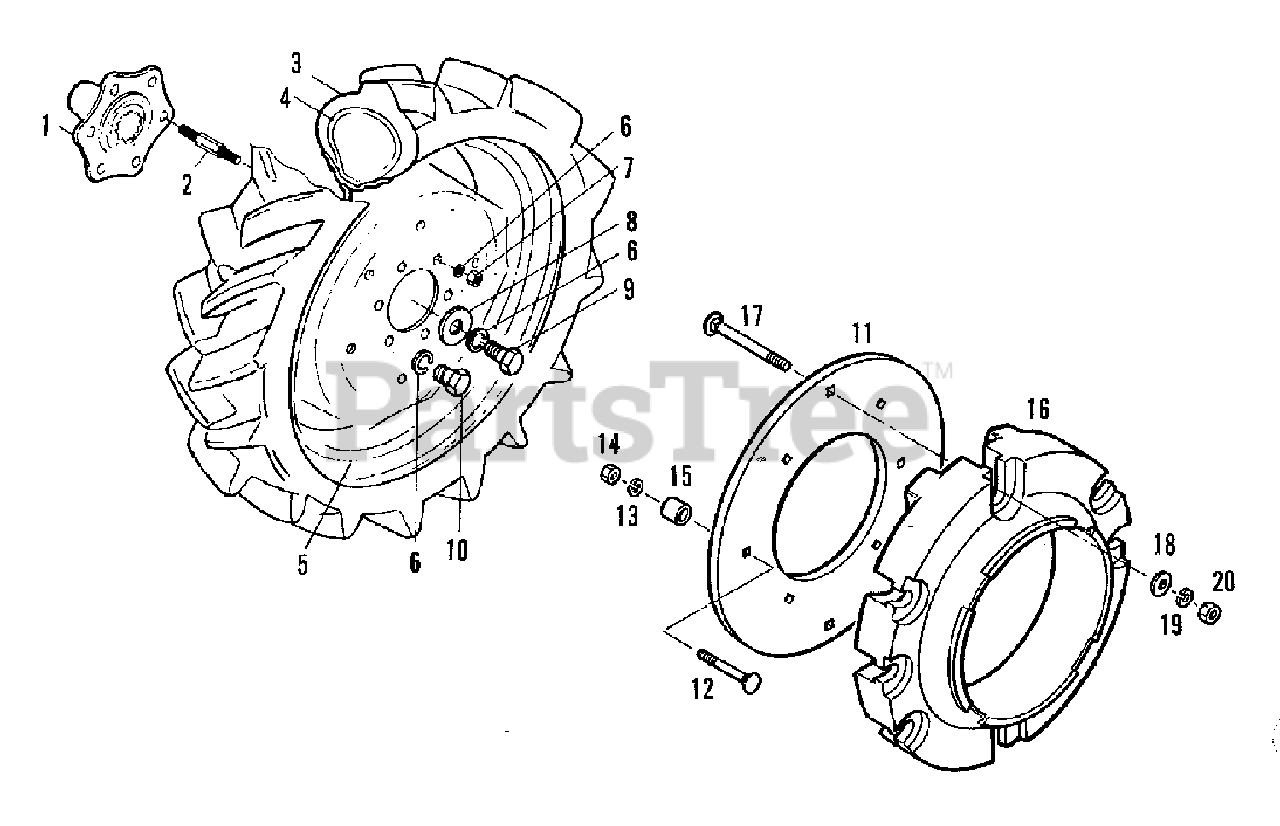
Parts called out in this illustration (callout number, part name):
1	HUB, rear wheel
3	TIRE (Obtain locally)
4	TUBE (Obtain locally)
6	LOCKWASHER, M16
8	PLATE, hub
11	ADAPTOR DISK
12	BOLT, rd. hd., sq. nk. f.b. No. nut.625-11 x 2.75 Gr 5, plt'd.
13	WASHER, lock, .625 plt'd.
14	NUT, .625-11 UNC2B plt'd.
16	WEIGHT, rear wheel
17	BOLT, rd. hd., sq. nk. f.b. No. nut.75-10 x5.00 Gr 5, plt'd.
18	WASHER, plain, SAE, .75 plt'd.
19	WASHER, lock, .750 plt'd.
20	NUT, .750-10 UNC-2B plt'd.
